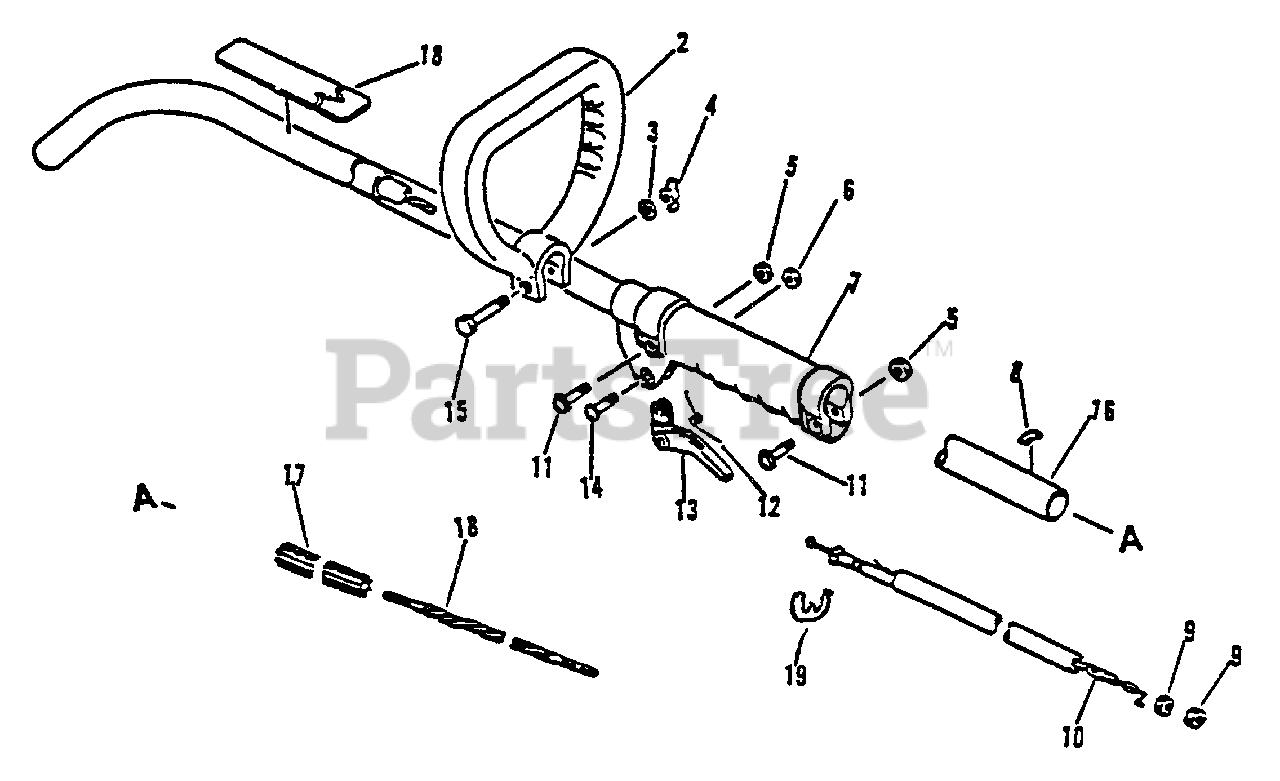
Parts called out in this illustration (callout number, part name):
2	HANDLE - FRONT
3	WASHER 6.5×11.5×0.8
4	NUT, WING 6
5	NUT M5
6	NUT, LOCK M5
10	CABLE, THROTTLE
11	SCREW 5×25
12	SPRING, THROTTLE
13	TRIGGER, THROTTLE
15	BOLT - 6×40
16	DRIVESHAFT - FLEXIBLE
17	LINER - FLEXIBLE
18	LABEL - CAUTION
19	RING, RETAINING - 5
